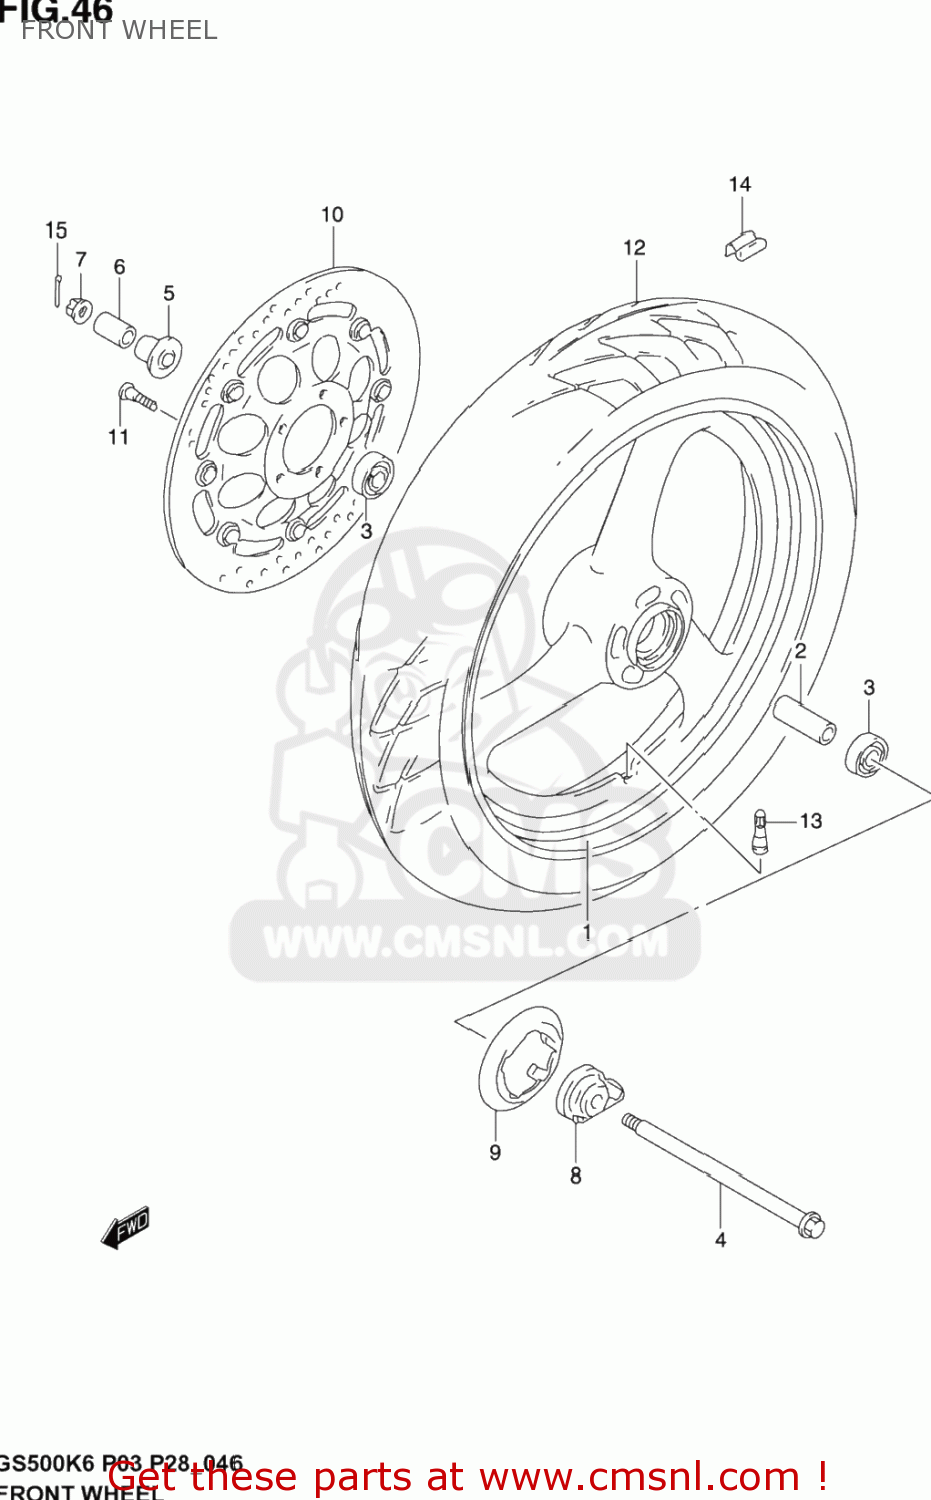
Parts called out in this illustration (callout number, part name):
1	WHEEL,FR(MT3.00X17)
2	SPACER(15.3X21.7X63)
3	BEARING
4	AXLE,FR
5	SPACER, FRONT AXLE RH
6	SPACER, FRONT AXLE RH
7	NUT
8	BOX ASSY,SPEEDOMETER GEAR
9	COVER, FRONT HUB LH (BLACK)
10	DISC, FRONT LH
11	BOLT 8X33
12	TIRE, FRONT,110/70-17 54H
13	VALVE
14	BALANCER,WHEEL(10G)
15	PIN
